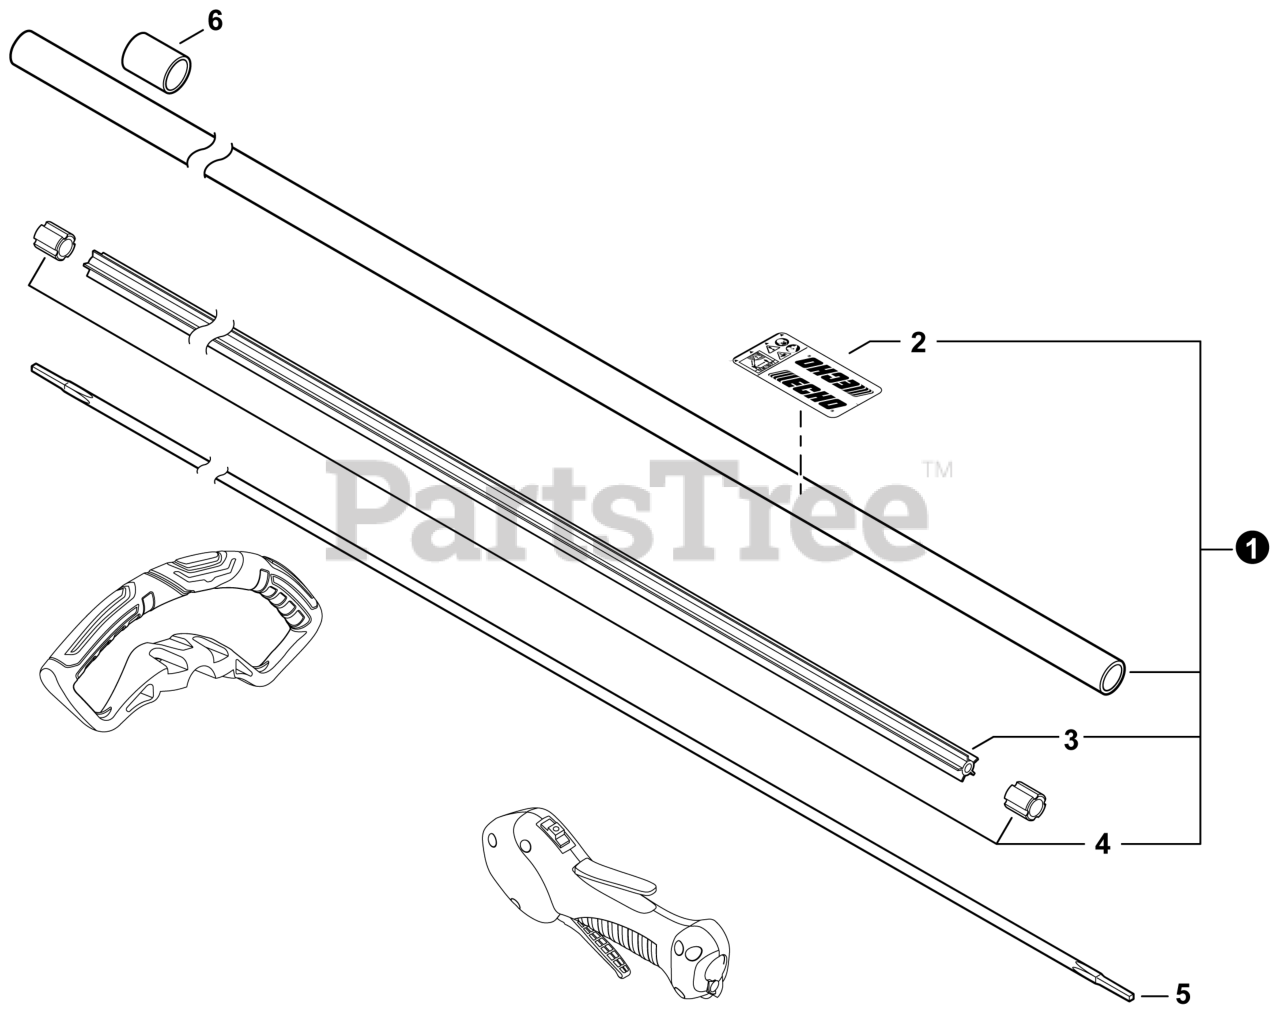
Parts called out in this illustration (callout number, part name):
1	MAIN PIPE ASSY
2	LABEL - CAUTION
3	LINER - FLEXIBLE
5	DRIVESHAFT - FLEXIBLE
6	COLLAR - 22
